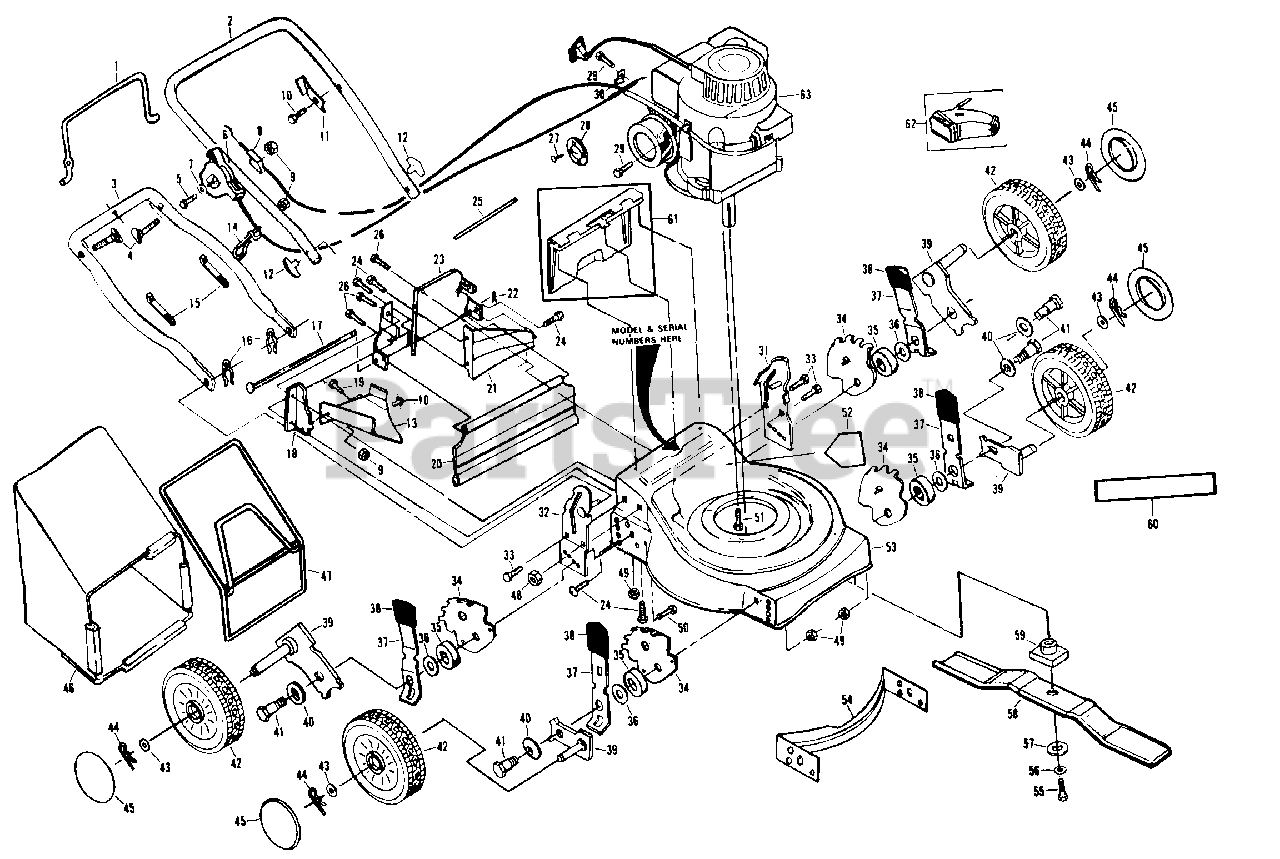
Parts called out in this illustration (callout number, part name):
1	Control Bar (AYP part number)
2	Upper Handle (AYP part number)
3	Lower Handle (AYP part number)
4	Handle Bolt
5	Machine Screw (AYP part number)
6	Throttle Control (AYP part number)
7	Flat Washer (AYP part number)
8	Engine Zone Cable (AYP part number)
9	Locknut (AYP part number)
10	Hex Washer Head Screw (AYP part number)
11	Up-Stop Bracket (AYP part number)
12	Handle Knob (AYP part number)
13	Discharge Baffle (AYP part number)
14	Rope Guide (AYP part number)
15	Wire Tie (AYP part number)
16	Hairpin Cotter (AYP part number)
17	Skirt Rod (AYP part number)
18	Side Baffle (AYP part number)
19	Machine Screw (AYP part number)
20	Rear Skirt (AYP part number)
21	Rear Baffle (AYP part number)
22	Retainer Clip (AYP part number)
23	Back Plate (AYP part number)
24	Hex Tapping Screw (AYP part number)
25	Hinge Rod (Door) (AYP part number)
26	Self Tapping Screw (AYP part number)
27	Screw (AYP part number)
28	Muffler Deflector
29	Thread Rolling Screw (AYP part number)
30	Cable Clamp
31	Handle Bracket Assembly (Left) (AYP part number)
32	Handle Bracket Assembly (Right)
33	Thread Cutting Screw (AYP part number)
34	Wheel Adjusting Bracket (AYP part number)
35	Spacer (AYP part number)
36	Flat Washer (AYP part number)
37	Selector Spring (AYP part number)
38	Selector Knob (AYP part number)
39	Axle Arm Assembly (AYP part number)
40	Belleville Washer (AYP part number)
41	Shoulder Bolt (AYP part number)
42	Wheel Assembly (AYP part number)
43	Flat Washer (AYP part number)
44	Retainer Clip (AYP part number)
45	Hubcap (AYP part number)
46	Grassbag Assembly
47	Catcher Frame Assembly
48	Locknut (AYP part number)
49	Locknut (AYP part number)
50	Carriage Bolt (AYP part number)
51	Hex Head Thread Rolling Screw (AYP part number)
52	Danger Decal (AYP part number)
53	Housing Assembly (AYP part number)
54	Front Baffle (AYP part number)
55	Hex Head Screw
56	Helical Washer (AYP part number)
57	Hardened Washer (AYP part number)
58	20" Blade
59	Blade Adapter (AYP part number)
60	"Poulan" Decal (AYP part number)
61	Rear Door Kit (AYP part number)
